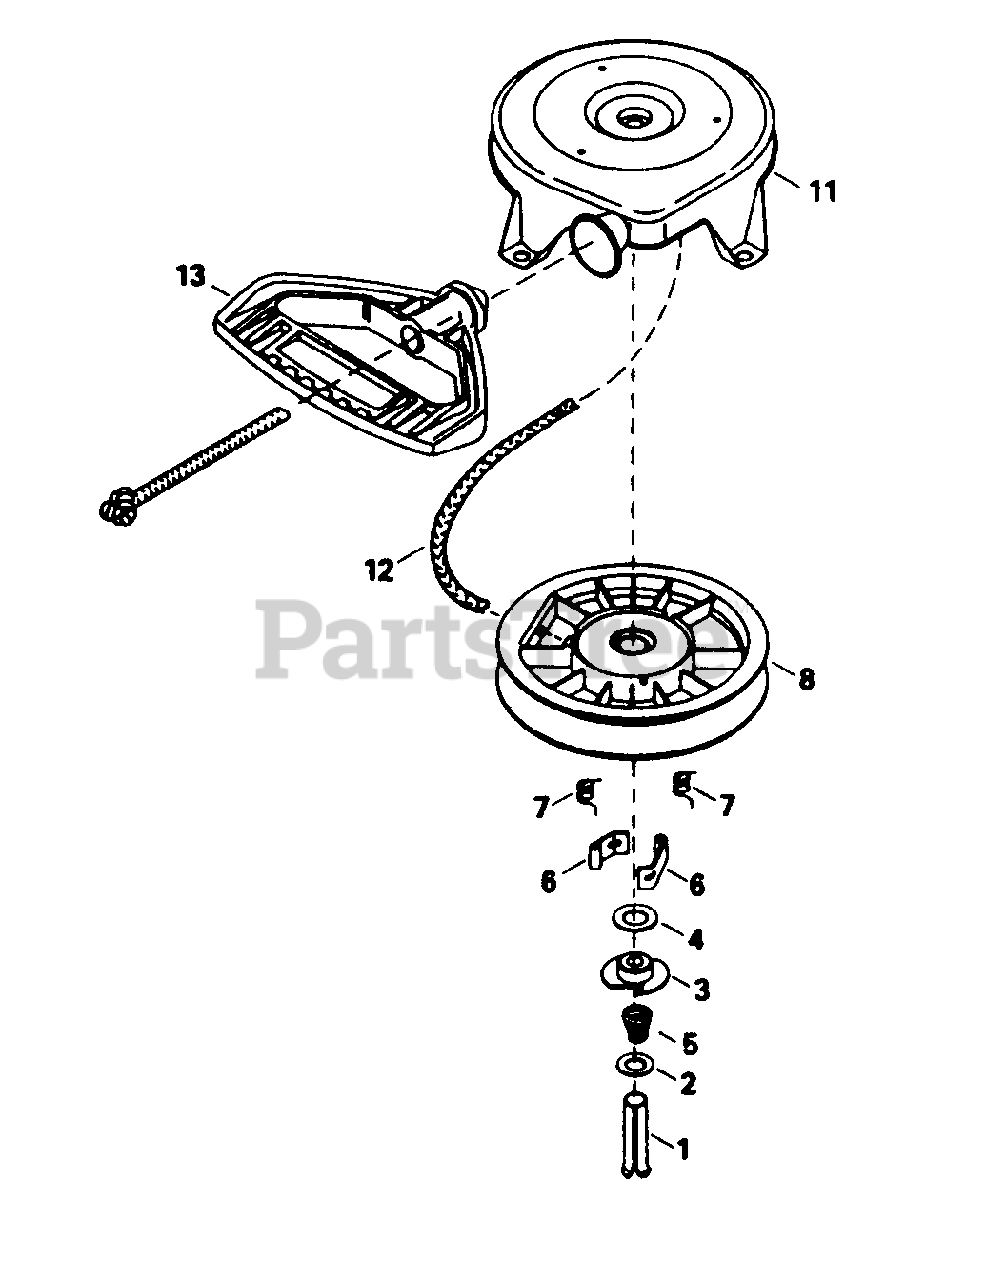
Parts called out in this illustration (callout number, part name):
1	Pin, Spring
5	Spring, Brake
6	Dog, Starter
7	Spring, Dog
8	Pulley 8 Rewind Spring Ass'y.
11	Housing Ass'y., Starter
12	Rope, Starter (Length 114" & 11/64" Dia.)
13	Handle, Mitten Grip
